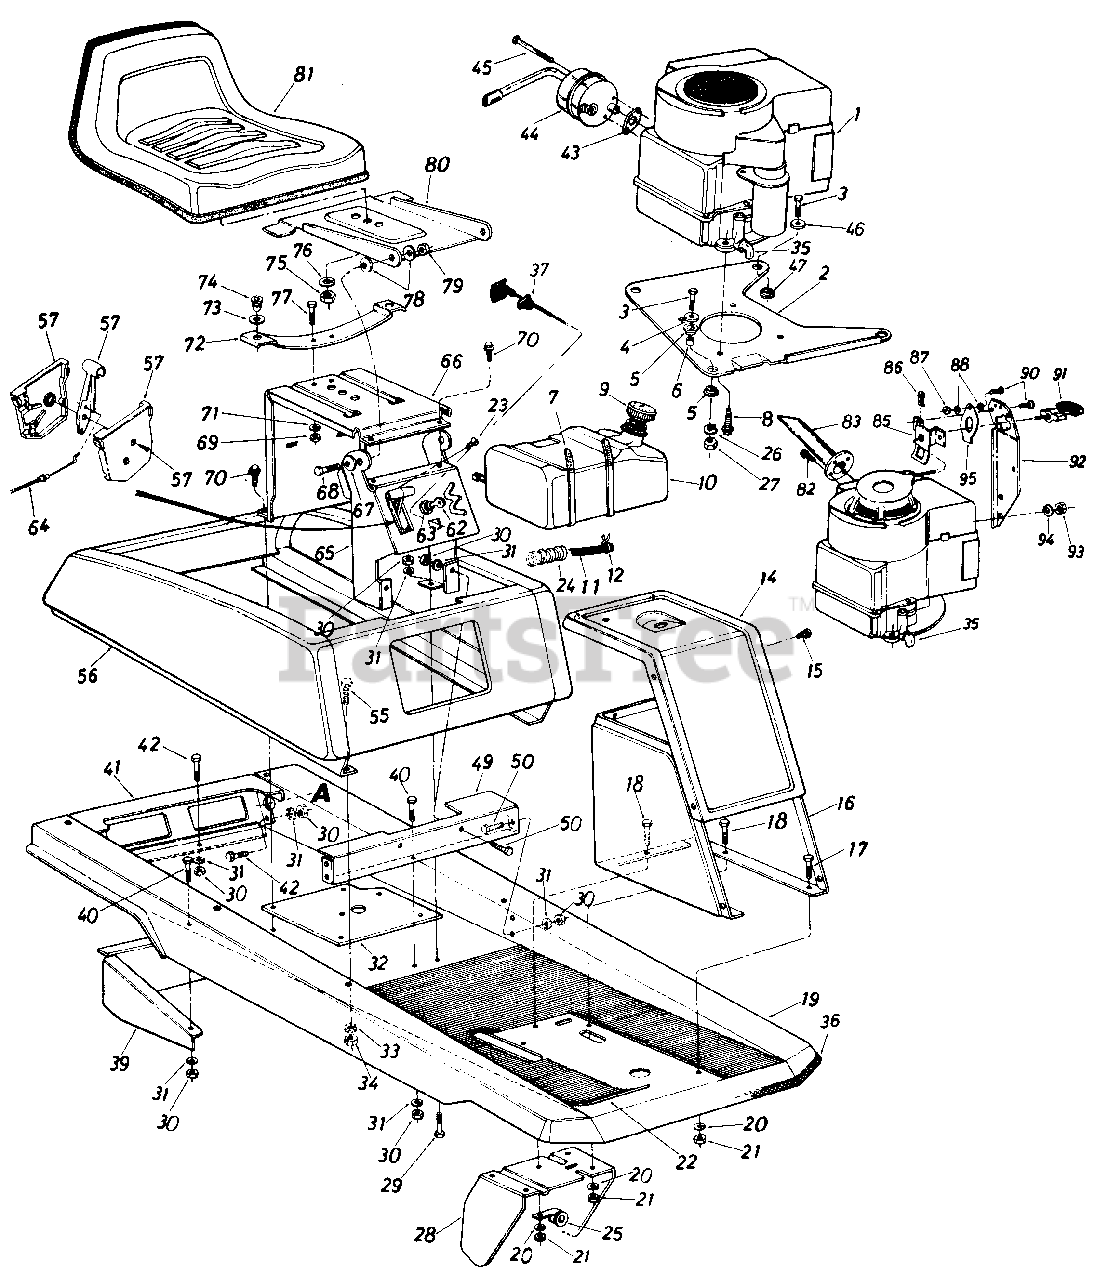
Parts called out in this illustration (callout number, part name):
1	Engine
2	Engine Mounting Plate
3	Hex Bolt 5/16-24 x 1.25" Lg.
4	Fl-Wash. .330" I.D. x 1.125n O.D.
5	Engine Mounting Grommet
6	Spacer .315" I.D. x .50" O.D. x.520" Lg.
7	Cable Tie 30.6 Lg.
8	Hex Wash. Hd. Self-Tap Scr. 3/8-16 x 1.25" Lg.
9	Gas Gauge
10	Fuel Tank
11	Gas Line
12	Hose Clamp-.406" Dia.
22	Floor Mat
23	Truss Mach. AB-Tap Scr. #10 x .50" Lg.
24	Convoluted Conduit
25	Clamp
26	L-Wash. 5/16 I.D.
27	Hex Nut 5/16-24 Thd.
28	Clutch-Brake Pedal Ass'y.
29	Hex Bolt 5/16-18 x .75n Lg
30	Hex Nut 5/16-18 Thd.
31	L-Wash. 5/16 I.D.
32	Mounting Brkt. Variable Speed Pulley
33	L-Wash. 1/4" I.D.
34	Hex Nut 1/4-20 Thd.
35	90ø Elbow Male To Female
36	Trim Strip 18" Lg.
37	Choke Control
39	Transaxle Support Ass'y.
40	Hex Bolt 5/16-18 x .75" Lg.
43	Exhaust Gasket
44	Muffler Ass'y.
45	Shld. Bolt
46	Fl-Wash. .330" I.D. x 1.25" O.D.
47	Flange Wash. 320" I.D. x .750" O.D.
49	Seat Support & Frame Brkt.
50	Hex Bolt 5/16-18 x .75" Lg.*
55	Hex Bolt 1/4-20 x .50" Lg.*
57	Throttle Control Box Ass'y.
62	Ignition Key
63	Ignition Switch
64	Throttle Control Wire-35"
65	Front Seat Bracket
66	Rear Seat Bracket
67	Bell-Wash. .345" I.D. x .88" O.D.
68	Hex Bolt 5/16-18 x .75" Lg.*
69	Hex Nut 5/16-18 Thd.*
70	Hex Self-Tap Scr. 5/16-18 x .75" Lg.
71	L-Wash. 1/4" I.D.*
72	Seat Spring
73	Fl-Wash. .531" I.D. x .930" O.D.
74	Grommet
75	Hex Nut 1/2-13 Thd.*
76	L-Wash. 1/2" I.D.*
77	Hex Bolt 1/4-20 x .75" Lg.*
78	Bell-Wash. .345" I.D. x .88" O.D.
79	Hex Cent. L-Nut 5/16-18 Thd.
80	Seat Pivot Bracket
81	Seat Ass'y. Comp.
82	Hex Wash. Hd. TT-Tap Scr. 8-32 x .50" Lg.
83	Exhaust Pipe Ass'y.
85	Switch Brkt. Ass'y
86	Speed Nut #10-24 U-Type
87	Hex Nut #10-24 Thd.*
88	Fiber Washer
90	Truss Mach. Scr. #10 x .50" Lg.*
91	Plastic Handle
92	Rope Handle Bracket
93	Hex Nut 5/16-18 Thd.*
94	L-Wash. 5/16" I.D
95	Switch Spring
